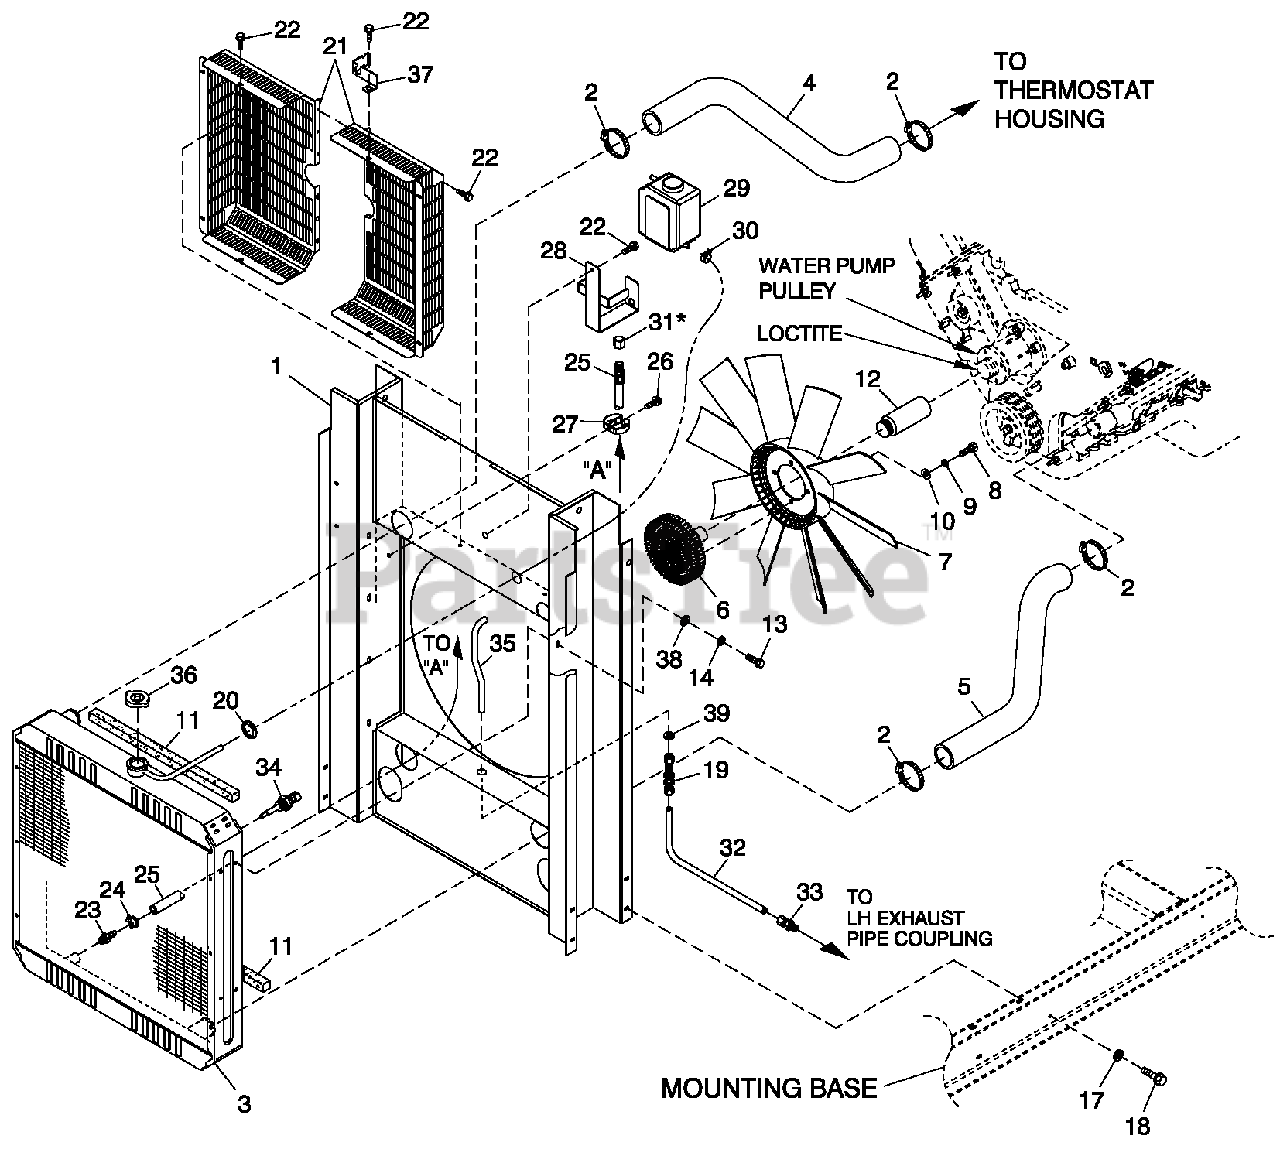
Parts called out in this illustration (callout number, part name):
1	WELDMENT RAD SUPPORT C3 (22")
2	CLAMP HOSE #28 1.32-2.25
3	RADIATOR581X 585 X 70 CPL LH
4	HOSE UPPER RADIATOR C3
5	HOSE LOWER RADIATOR C3
6	CLUTCH COOLING FAN
7	FAN 2Z' DIA 10 BLADE
8	SCREW HHCM10-1.5 X20G8.8
9	WASHER LOCKM10
10	WASHER FLAT 3/8-M10ZINC
11	TAPE FOAM 1X1 (23" LG)
12	SPACER FAN 6.8L
13	SCREW HHCM8-1.25X2 0G 8.8
14	WASHER LOCK M8-5/16
17	WASHER LOCK M6-1/4
18	SCREW HHFCM6-1.0X20 G8.8
19	FTG CMPN BLKHD3/8" OD TUBE BRS
20	GROMMET.75X.12X.50
21	GUARD FANC3 CPL
22	SCREW THF M6-1 X 16 NWAZ/JS
23	BARBED STR 3/B NPT X 3/8
24	CLAMP HOSE .38-.87
25	HOSE DRAIN ASSY 28"
26	SCREW HHTT M4-0.7X8BP
27	SPRING CLP HOLDER .37-.62
28	BRKT COOLANT RECOVERYTANK
29	TANK COOLANT RECOVERY
30	CLAMP HOSE BAND 1/4
31	CAP HEX 1/4 NPT BRASS
32	TUBE FAN CLUTCH PREHTR LOWR C3
33	FTG CM PR 3/8TUBE X 3/8 NPT W/FERL
34	PROBE COOLANT LEVEL 3/8NPTF (USE WITH HARN P/N 0F599 0 & 0F5991)
35	TUBE FAN CLUTCH PREHTR UP PR C2
36	CAP RADIATOR 13 PSI
37	BRACKET SIGNAL CONDITIONER
38	WASHER FLAT 5/16-M8ZINC
39	WASHER FLAT 9/16 ZINC
